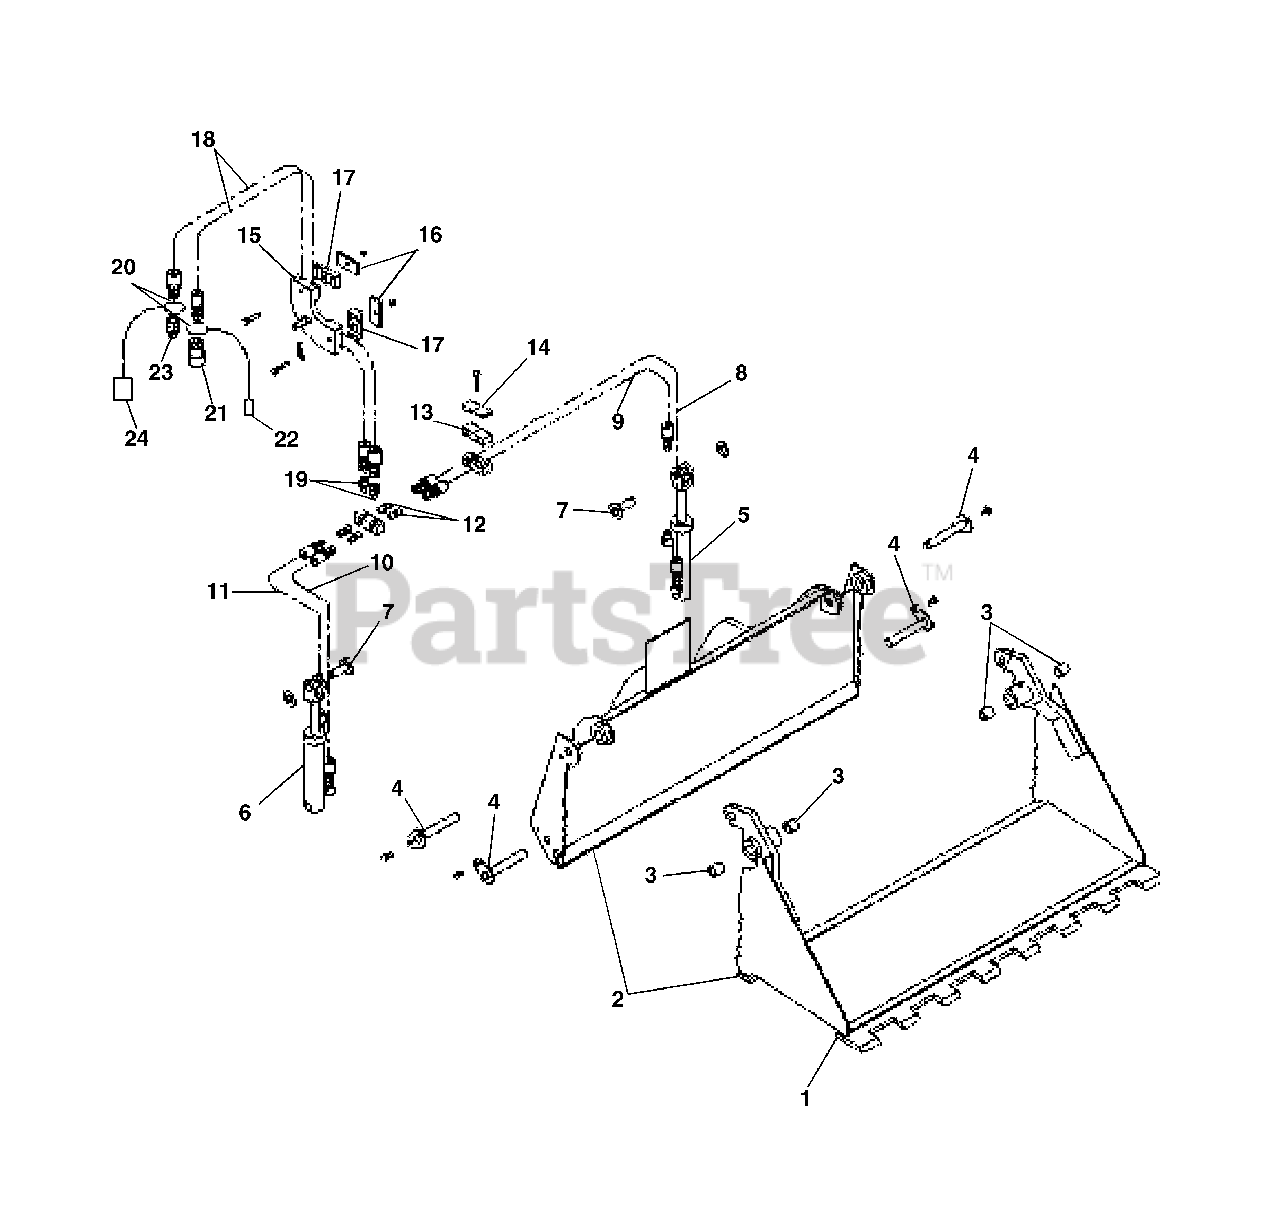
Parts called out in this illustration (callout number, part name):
1	Bar, Tooth
2	Cutting Edge, Bottom
4	Pin, Bucket Pivot
5	Cylinder, 4N1 Bucket Left Hand
6	Cylinder, 4N1 Bucket Right Hand
7	Pin, Cylinder Top
8	Hose, Hydraulic
9	Hose, Hydraulic
10	Hose, Hydraulic
11	Hose, Hydraulic
12	Fitting, Hydraulic Straight
13	Clamp, Dual Hose .375 I.D. Hose
14	Plate, Cover
15	Bracket, Attachment Hose-Assembly
16	Plate, Cover
17	Clamp, Dual Hose
18	Hose, Hydraulic
19	Fitting, Hydraulic Straight
20	Seal, Bonded
21	Coupling, Female Quick
22	Plug, Dust .50 Quick Coupler
23	Coupler, Male Quick
24	Cap, Dust .50 Quick Coupler
